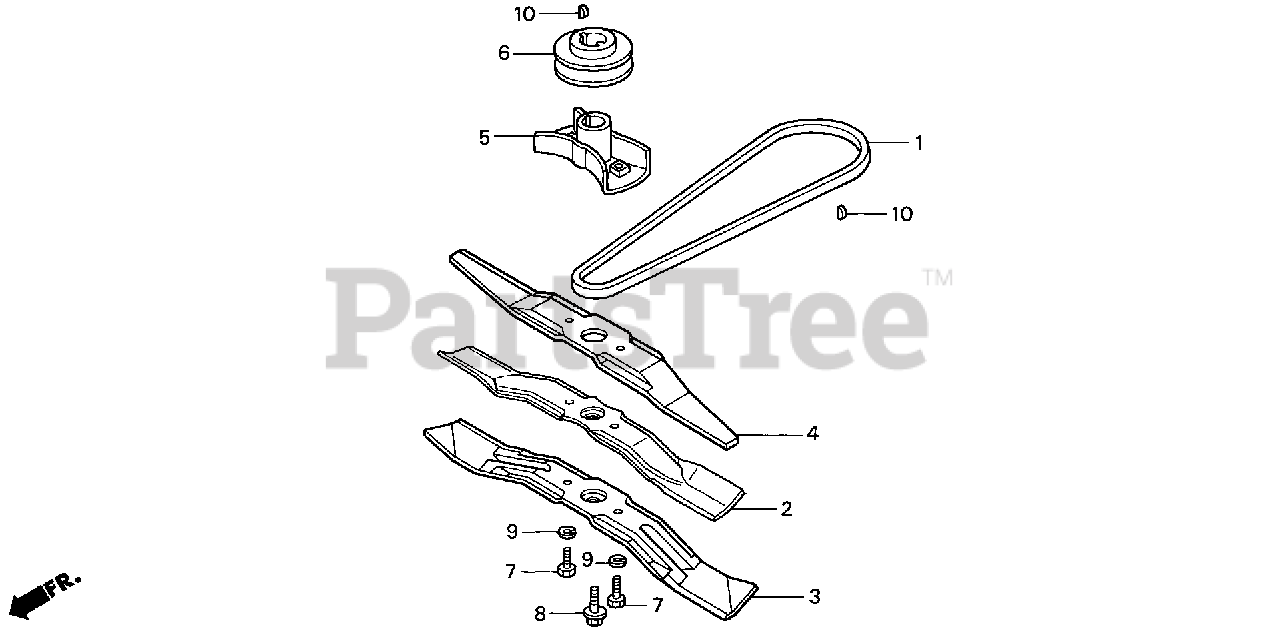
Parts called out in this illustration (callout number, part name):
1	V-BELT (3L-36.3)
2	BLADE, ROTARY
3	BLADE, MULCHING
3	BLADE, ROTARY (PCD=88MM)
4	BLADE, ROTARY (UPPER) (PCD=88MM)
5	KIT, BLADE HOLDER
6	PULLEY, DRIVE
7	BOLT, HEX. (10X20)
8	BOLT, FLANGE (3/8-24X1")
9	WASHER, SPRING (10MM)
10	KEY, WOODRUFF (3/16X5/8)
